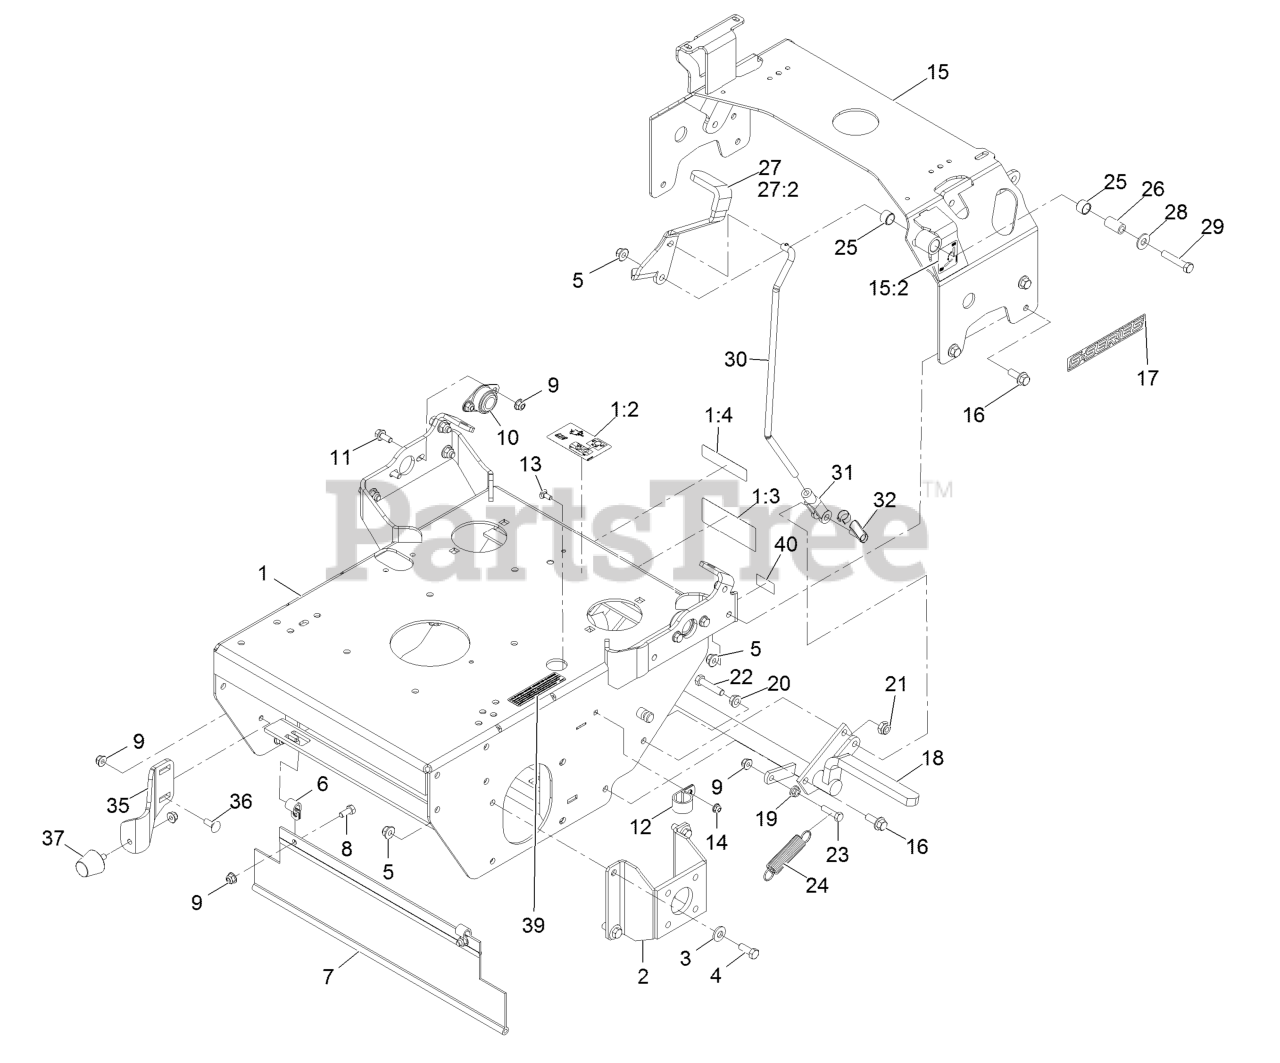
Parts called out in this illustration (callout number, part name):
1	ASM, Engine Deck W/ Decals
1:2	Decal-Drive Release
1:3	Decal-Warning, Sulky
1:4	Decal-Warning
2	Mount, Wheel Motor 36"
3	Washer-Spring Disc 3/8
4	Screw-HH 3/8-16 X 1
5	Nut-Nyloc 3/8-16 Flg
6	Clip-Loom
7	Shield-Drag
8	Screw-HH 5/16-18 X 3/4
9	Nut-Nyloc 5/16-18 Flg
10	Bearing-Flanged
11	Screw-HH Flg 5/16-18 X 3/4
12	Clip-Loom
13	Bolt-Carriage 1/4-20 X 5/8
14	Nut-Nyloc 1/4-20 Flg
15	ASM, Tank Support W/ Decal
15:2	Decal-Park Brake, CE
16	Screw HHF 3/8-16 X 1
17	Decal-S-Series
18	Shaft-Cross, Brake
19	Nut-Whizlock 5/16-18
20	Nut-Whizlock 3/8-16
21	Nut-Lock, NI
22	Screw-HH 3/8-16 X 1 3/4
23	Screw-HH 5/16-18 X 1 1/4
25	Sleeve-Bushing
26	Bushing-Pivot
27	ASM, Brake Lever W/ Grip
27:2	Grip-Lever
28	Washer-3/8 Std
29	Screw-HH 3/8-16 X 2
30	Linkage, Brake
31	Yoke-Linkage, Brake
32	Pin-Clevis Spring 3/8
35	Bracket-Bumper
36	Bolt-Carriage 5/16-18 X 7/8
37	Bumper-Rubber
39	Decal-Arrester, Spark
40	Decal-Patent
